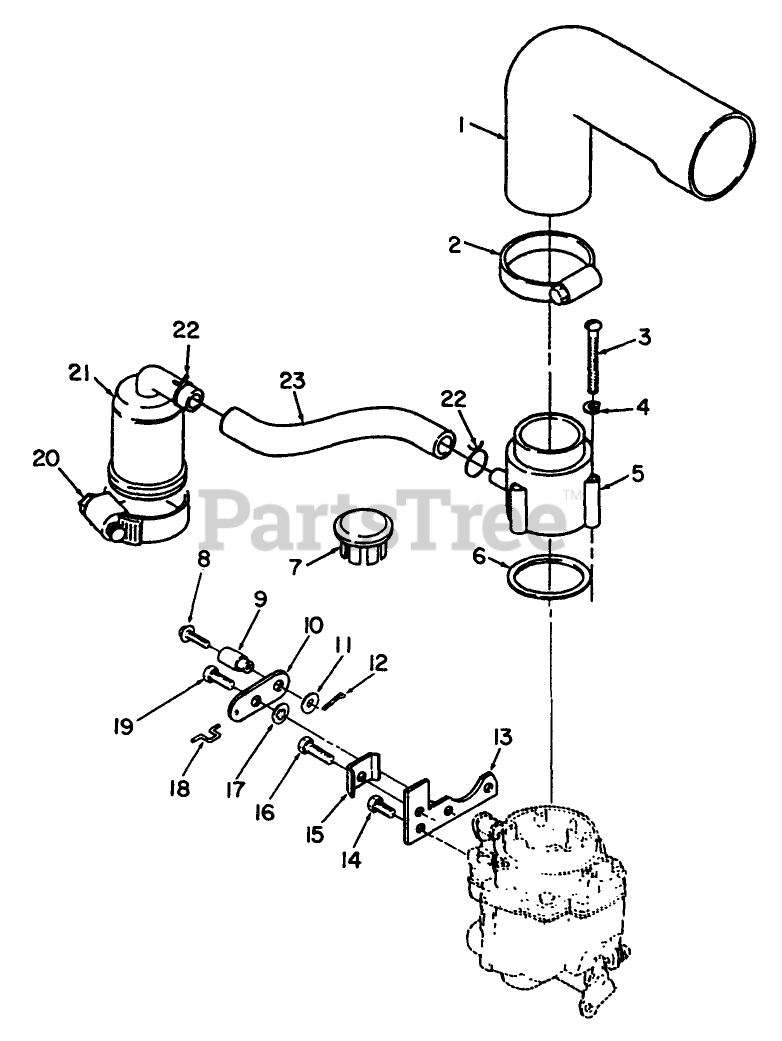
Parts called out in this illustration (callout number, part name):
1	INLET ASM
2	HOSE CLAMP
3	RD HD MACH SCREW
4	WASHER-LOCK
5	ADAPTER
7	PLUG, HOLE
8	SCREW
9	SWIVEL
10	SWIVEL-CHOKE
11	WIRE CLAMP
12	PIN-COTTER
13	BRACKET
14	SCREW-HWH
16	SCREW-TAPPING
17	WASHER-LOCK, INT
18	LINK-CHOKE
19	BOLT-SHOULDER
20	CLAMP
21	BREATHER TUBE ASSY
22	CLAMP
23	BREATHER HOSE
